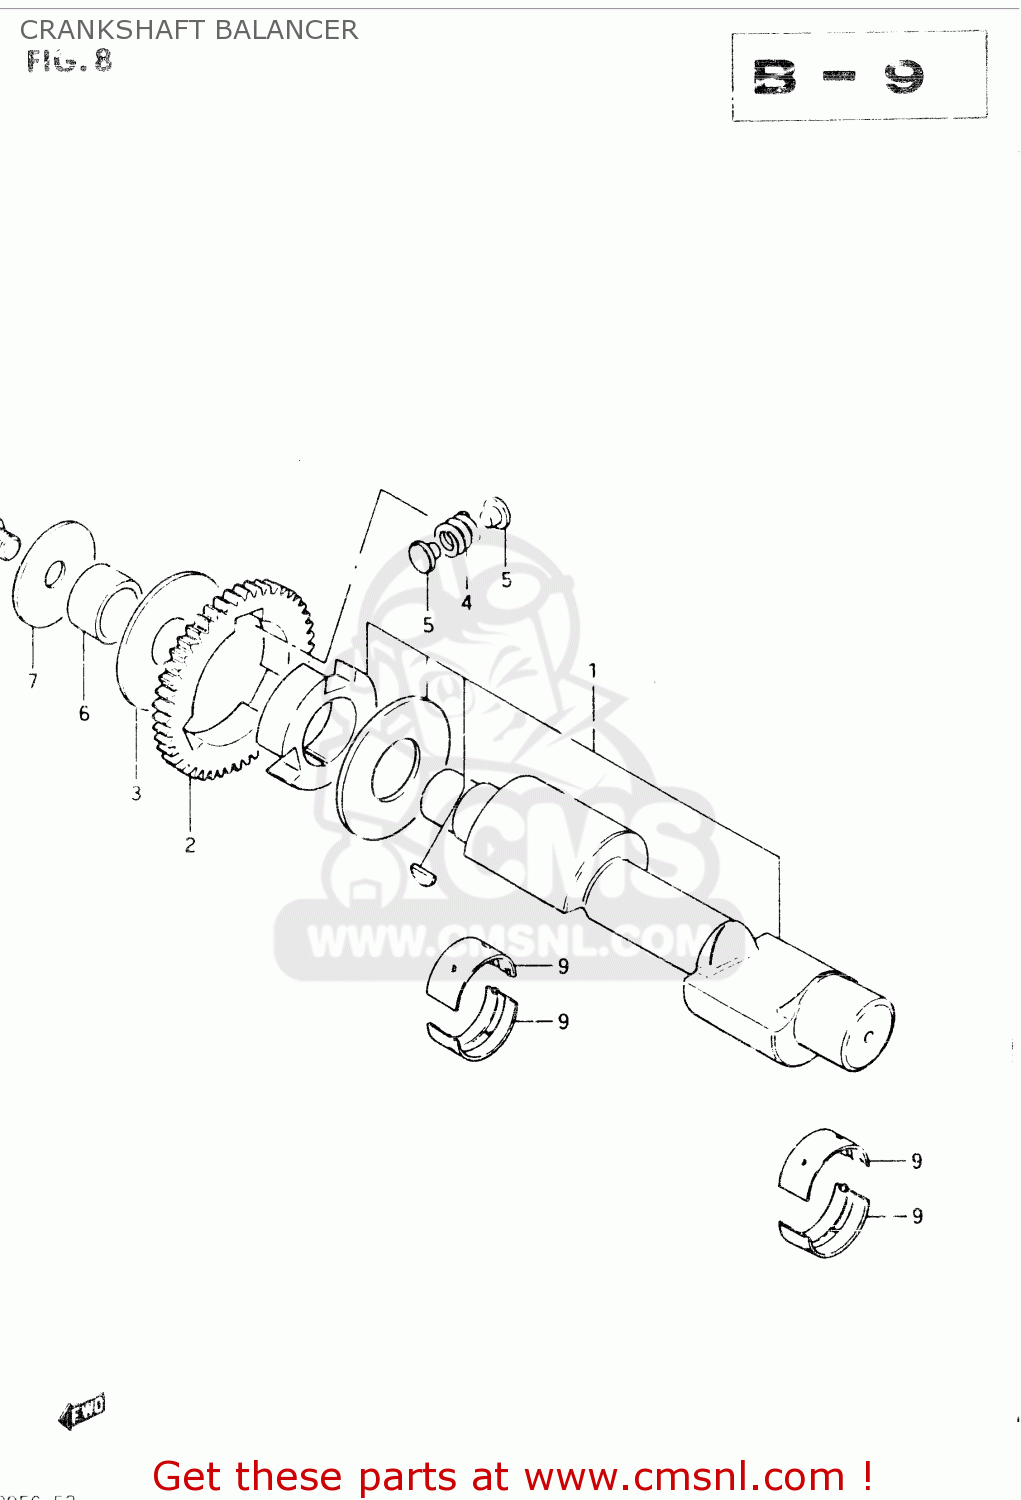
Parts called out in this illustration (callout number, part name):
1	BALANCER,CRANKSHAFT
2	GEAR,CRANK BALANCER DRIVE
3	WASHER
4	SPRING
5	PIN
6	SPACER
7	WASHER(12X50X3)
8	BOLT
9	METAL CRANKSHAFT
